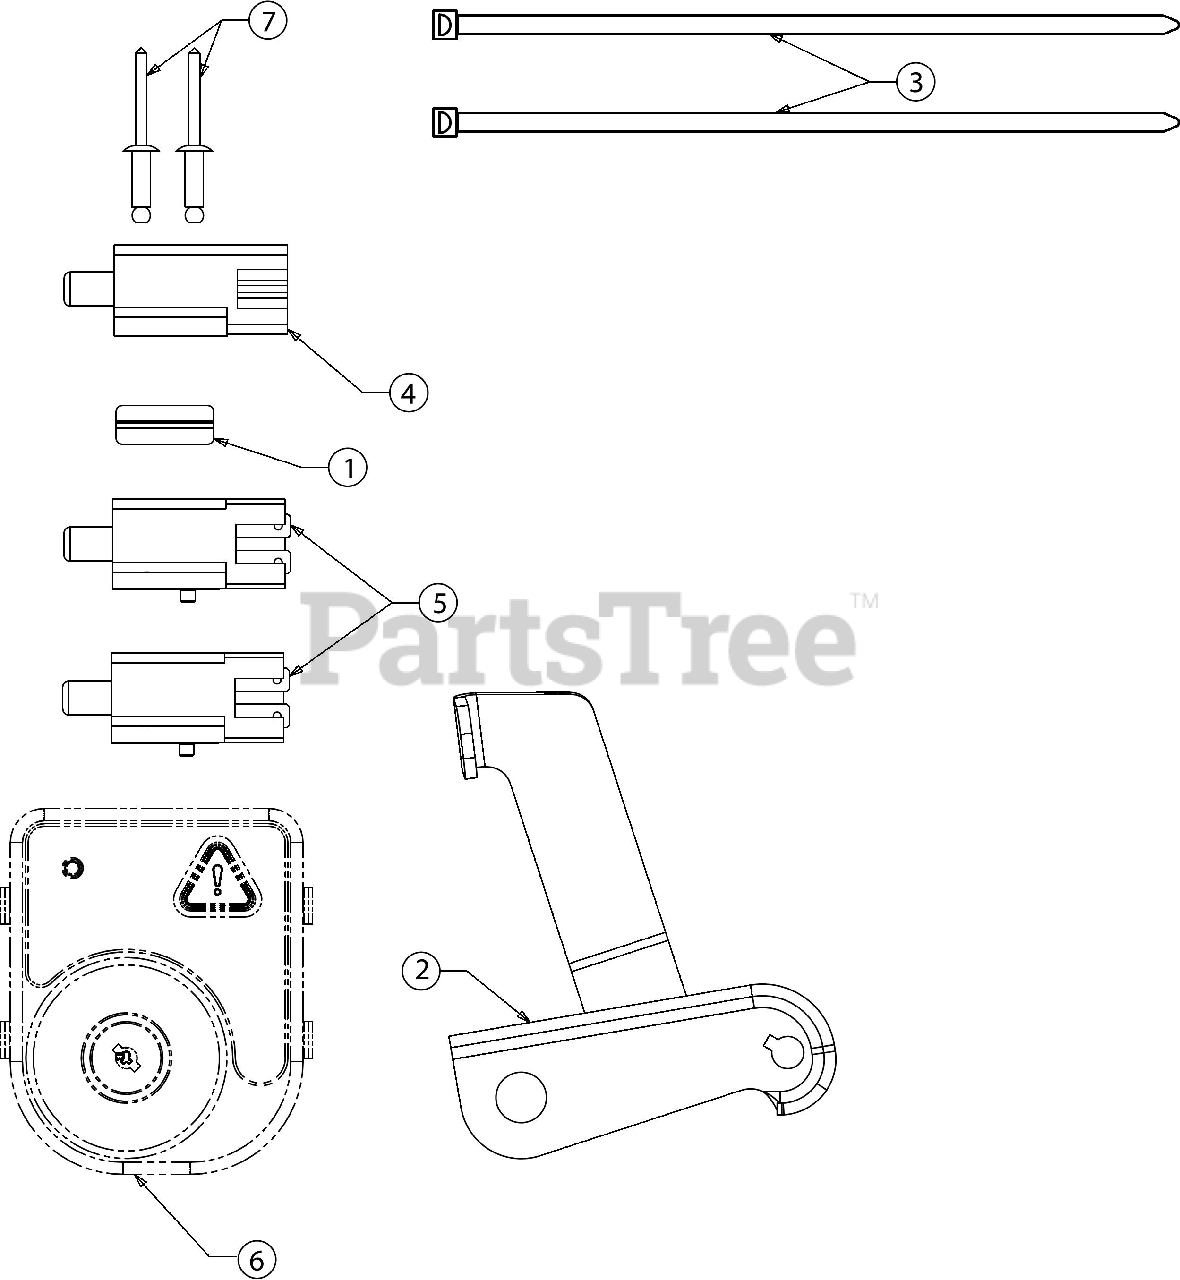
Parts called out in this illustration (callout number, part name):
1	PLATE-SWITCH
2	LATCH BRACKET
3	CABLE TIE 7"
4	SWITCH
5	INTERLOCK SWITCH (NO/NC)
6	IGNITION MODULE SWITCH RMC (MAN PTO BLK)
7	POP RIVET .187 DIA
